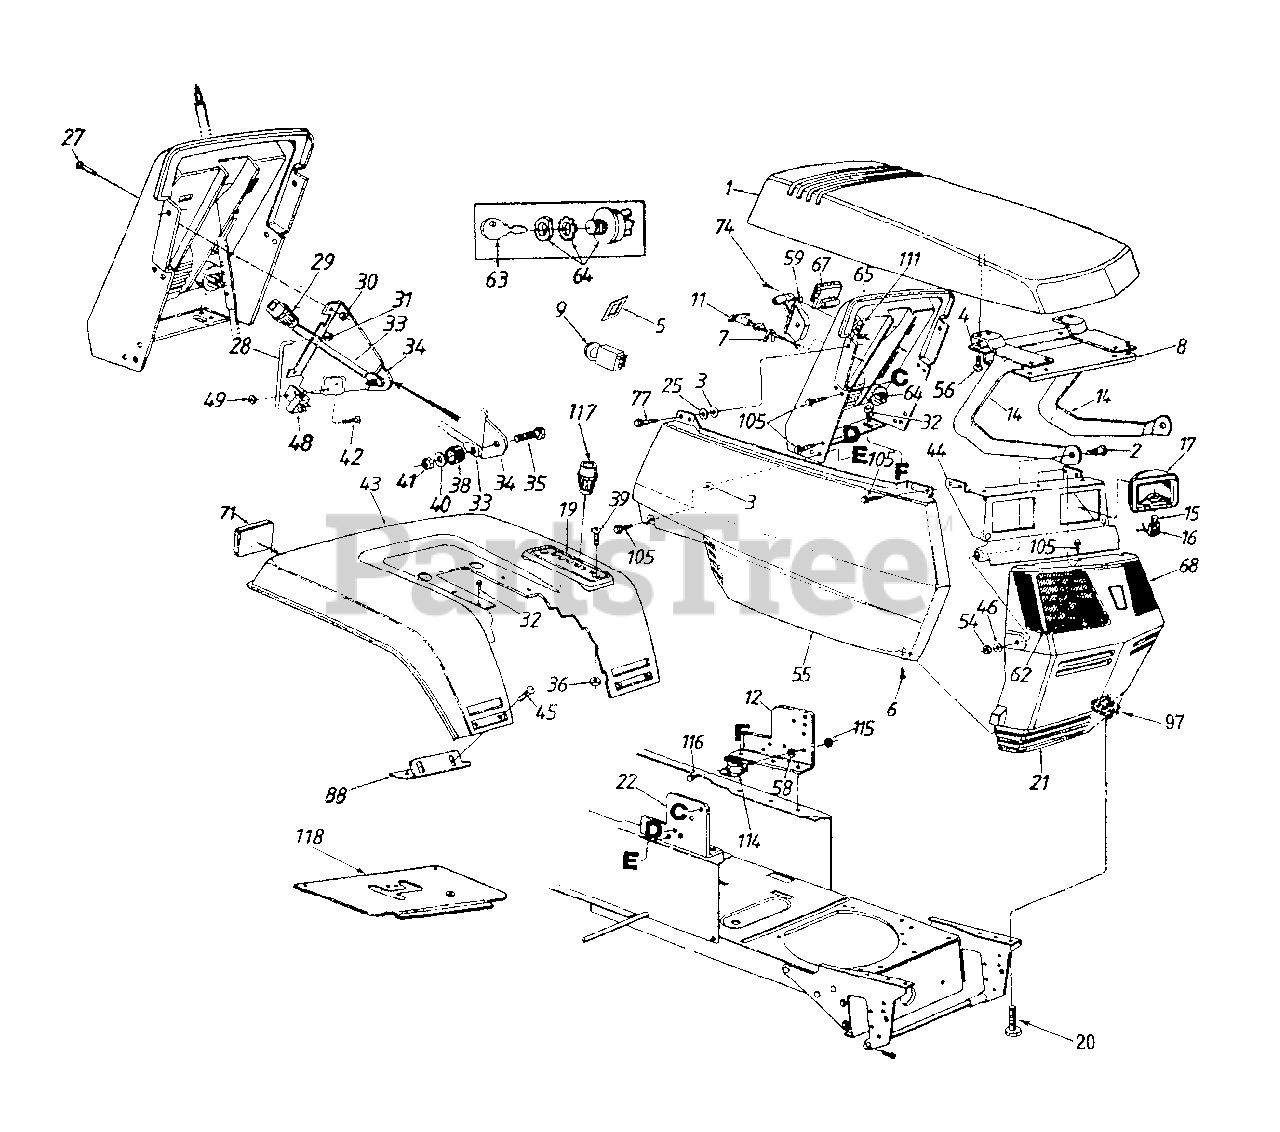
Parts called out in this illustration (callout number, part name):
1	Hood Ass'y.
2	Shld. Bolt .437" Dia. x .35"
3	Bolt Retainer 1/4" I.D.
6	Truss Mach. B-Tap Scr. #10 x .5" Lg.
7	Retainer Clip
11	Choke Control
16	Twist Lock-Lamp Socket
17	Headlight Housing
19	7-Speed Selector Plate
21	Grille
25	Fl-Wash. 1/4" I.D. x .93" O.D.
27	Truss Mach. Scr. 1/4-20 x .5" Lg.
28	Deck Control Rod
29	Knob-Blade Clutch
30	Hex Sems Nut 1/4-20 Thd.
31	Push Cap
32	Hex Wash. Hd. AB-Tap Scr.5/16 x .75" Lg.
33	PTO Lever
36	Hex Sems Nut 1/4-20 Thd.
38	Rubber Washer
39	Truss Mach. Scr. 1/4-20 x .75" Lg.
40	Fl-Wash. .281" I.D. x .73"
41	Hex L-Nut 1/4-20 Thd.
42	Truss Mach. Scr. #10-24 x .5" Lg.
46	Fl-Wash. .328" I.D. x .68" O.D.
48	Safety Switch
49	Hex Nut #10-24 Thd.
54	Hex Cent. L-Nut 5/16-18 Thd.
55	Side Cover-R.H.
56	Hx Wash. Hd. B-Tap Scr.1/4 x .5" Lg.
58	Ext. L-Wash. 1/4" I.D.
59	Throttle Control Box Ass'y.
62	Lens-R.H.
63	Ignition Key
64	Ignition Switch
65	Dash Panel
67	Ammeter
68	Lens-L.H.
71	Reflector
74	Truss Mach. AB-Tap Scr.#10 x .5" Lg.
77	Hex Wash. Hd. Tap Scr.1/4 x .75" Lg.
105	Hex Tap Scr. 1/4-20 x .5" Lg.
111	Speed Nut 1/4-20 Thd.
114	Solenoid
115	Hex Sems Nut 1/4-20 Thd.
116	Hex Bolt 1/4-20 x .5" Lg.
117	Shift Knob
